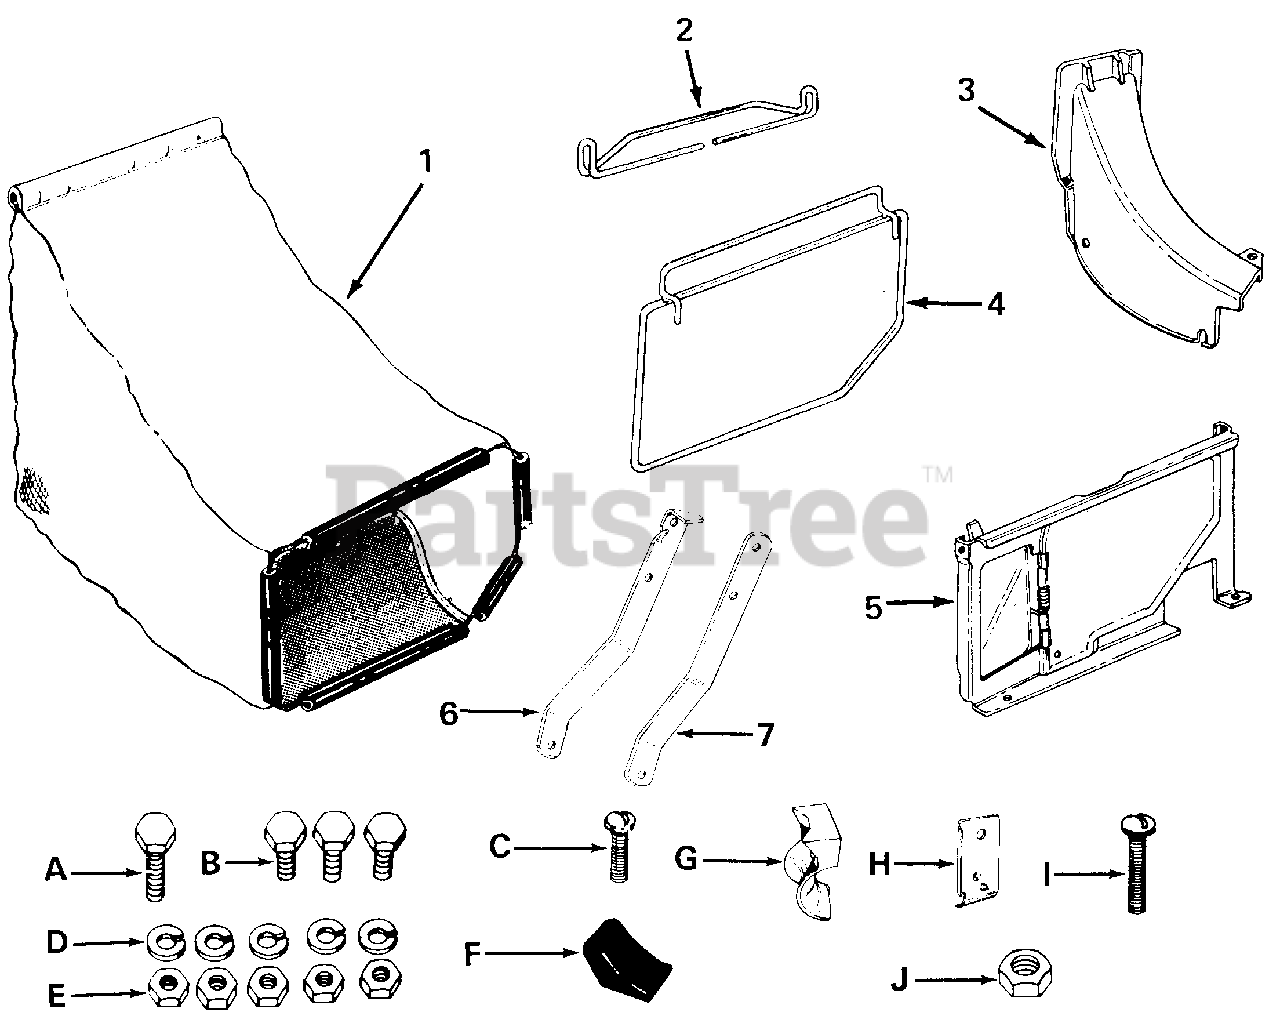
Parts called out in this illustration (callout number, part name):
1	Grass Bag
2	Grass Catcher Handle
3	Top Discharge Chute
4	Front Catcher Frame
5	Top Catcher Panel
6	Panel Support Bracket
7	Panel Support Bracket
A	Hex Bolt 1/4-20 x 5/8" Lg.*
B	Hex Bolt 1/4-20 x 1/2" Lg.*
C	Truss Machine Screw 1/4-20 x 1/2 Lg.*
D	Lock Washer 1/4" I.D.*
E	Hex Nut 1/4-20 Thread*
F	Door Grip
G	Rope Guide Half
H	Rope Retainer Clip
I	Truss Machine Screw 1/4-20 x 1.0 Lg.*
J	Hex Nut 5/16-18 Thread*
